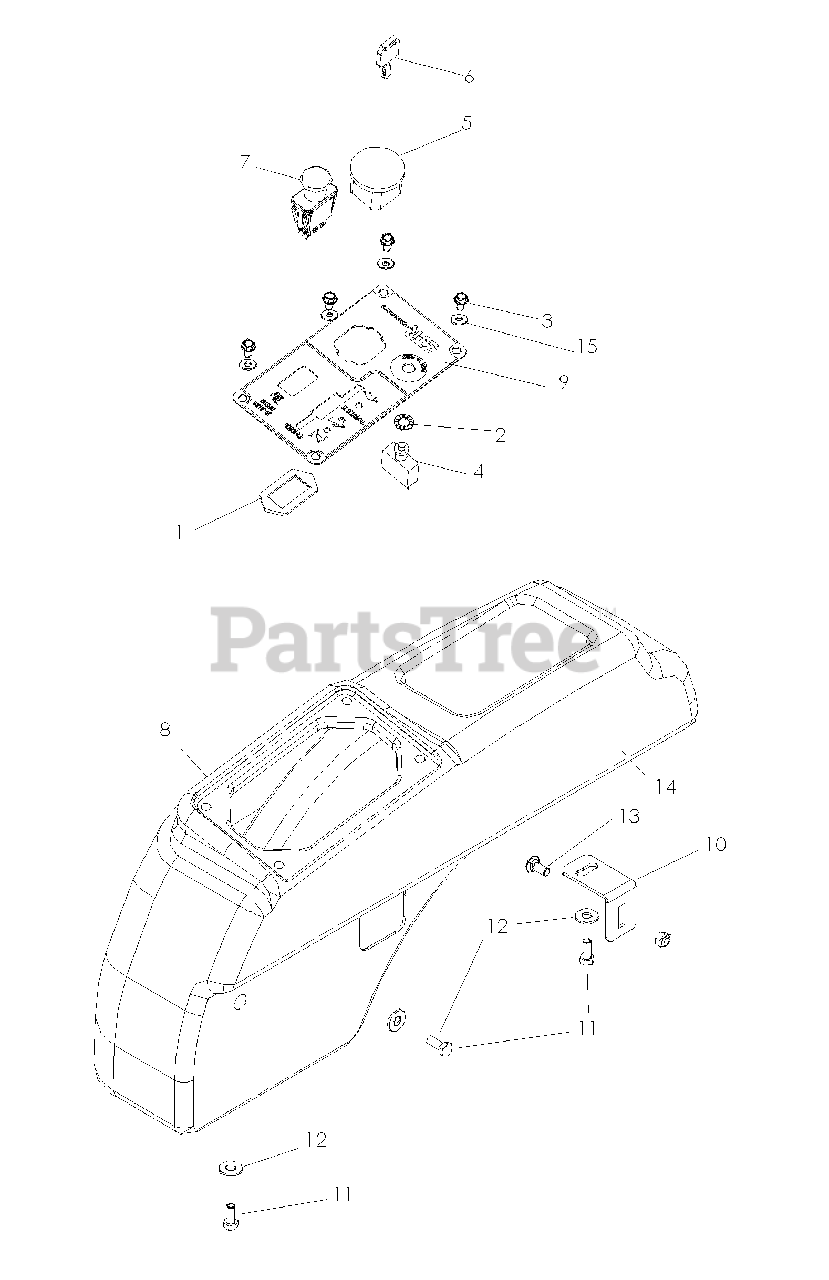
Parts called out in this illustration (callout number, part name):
1	PTO SWITCH RETAINER
2	7/16 INT TOOTH LWASH
3	SCREW 1/4 X 5/8
4	CIRCUIT BREAKER W58XB1A4A15
5	IGNITION SWITCH
6	KEY
7	SWITCH, BLADE
8	FENDER RH
9	CONTROL PANEL
10	TANK BRKT.
11	HCS 5/16C X 3/4
12	FLAT WASHER 5/16 SAE
13	BOLT 5/16C X 3/4" CARRIAGE
14	NUT 5/16 NYLOC
15	WASHER 1/4 FLAT
